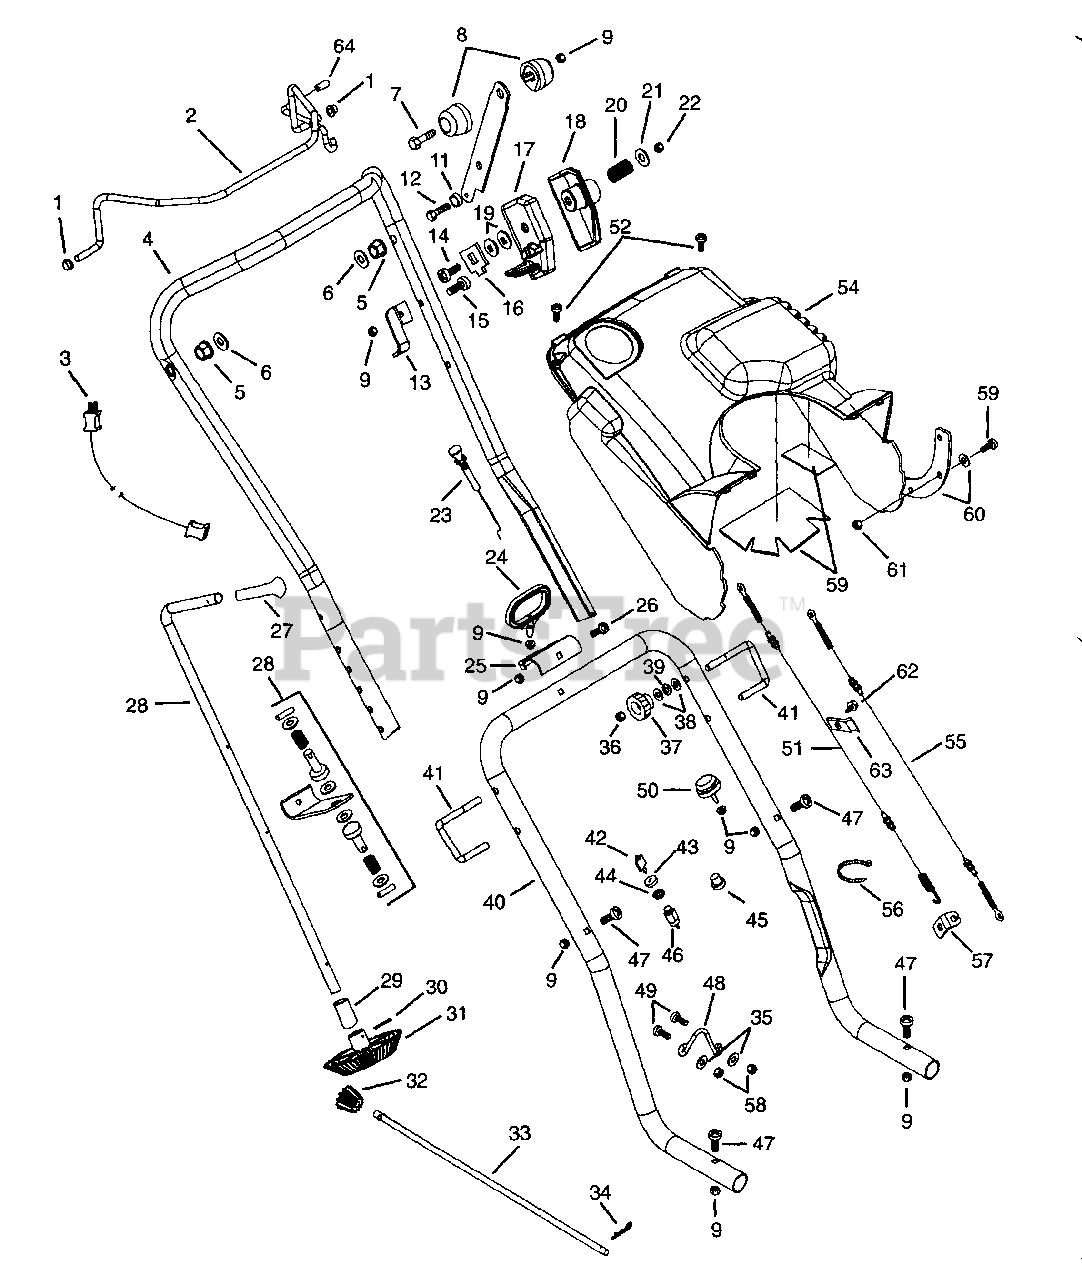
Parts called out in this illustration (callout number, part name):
1	NUT-PUSH .312 DIA. PAL
2	ENGINE BAIL WELDMENT
2	BAIL-CLUTCH CONTROL
3	CORD, EXTENSION
4	HANDLE BAR-UPPER
5	BSHG-FLG .325X.444X.440X.560
6	WSHR-FL-STL.344X.688X.065PL
7	BLT-HEX .25-20X1.38
8	KNOB
9	NUT-LK-FLG .250-20 PL BLK
10	LEVER-CHUTE DEFL CNTRL
11	SPACER .230X.310X.255
12	SCR-TAP 12-24X.50 HWH PL TR
13	ANCHOR-CABLE,CHUTE DEFL CNTRL
14	BLT-RDHDSQNK .38-16X2.25
15	BLT-RDHDSQNK .25-20X1.25 XLGPL
16	FRICTION PLATE
17	HSG-INNER,CHUTE DEFL CNTRL
18	HSG-OUTER,CHUTE DEFL CNTRL
19	FRICTION WASHER
20	SG-COMP .187X.56X1.62
21	WSHR-FL-STL .458X.750X.06 PL
22	NUT-LK TOP .375-16 GR C YWZC
23	CONTROL-CHOKE 3 HP
23	CONTROL-CHOKE 5 HP
24	HANDLE, RECOIL START
25	BRKT-STARTER HANDLE
26	BLT-RDHDSQNK .25-20X1.50 PL BL
27	KNOB
28	CRANK-CHUTE ASSY
28	SUPPORT-CHUTE CRANK
28	PIN-ROLL .125X1.38
28	WSHR-FL-STL .754X1.125X.062 PL
28	SG-COMP .105X.970X2.75 WLD55.5
28	SLEEVE-SPRING THRUST
28	WSHR-FRICTION .53X1.00X.094
29	BSHG-SLV .510X.753X2.00
30	@PIN-CTR .16X1.25 EXTPRSQCT YZ
31	GEAR-CRANK TRANSFER 48T
32	PINION-CRANK TRANSFER 12T
33	SHAFT CHUTE CRANK TRANSFER
34	PIN-HAIR INT .08X.38X1.42 YWZC
35	WSHR-FL-STL .194X.492X.047 PL
36	NUT-LK .312-18 GR A PL
37	KNOB
38	WSHR-FL-STL .328X.875X.062 PL
39	WSHR-LK .313X.078 PL MED
40	HANDLE BAR-LOWER
41	J BOLT .31-18
42	KEY -W/CAP
43	CAP - IGNITION SWITCH
44	NUT-PANEL .625-32 GRECO
45	PLUG-HOLE .50 DIA
46	KEY SWITCH ASSEMBLY
47	BLT-RDHDSQNK .25-20X1.75
48	GUIDE-ROPE
49	SCR-MCH 10-24X.75 PHD
50	PRIMER ASSY
51	CABLE-CLUTCH CONTROL
52	SCR-SPEC-TAP #10X1.0
53	SHEET-HEAT REFLECTIVE 3X5
53	SHEET-HEAT REFLECTIVE
54	COWL-REPLACEMENT
54	COWL ASSEMBLY
55	CABLE-CHUTE DEFLECTOR CONTROL
56	CABLE TIE LG 5-1/2
56	CABLE TIE .50 BUNDLE X3.12X18#
57	BRKT-ANGLE,DEFLECTOR CONTROL
58	NUT-LK 10-24 NY PL
59	SCR-MCH 10-24X.50 PHD
59	SCR-TAP 12-24X.50 HWH TR BLACK
60	WSHR-FL-STL .250X.562X.049 PL
60	PLATE-COWL RETAINER
61	NUT-LK 10-24 NY PL
62	SCR-TAP 10-16X .75 HWH PL SD
63	CABLE CLAMP NON SKID
64	CAP, VINYL, .25 ID
